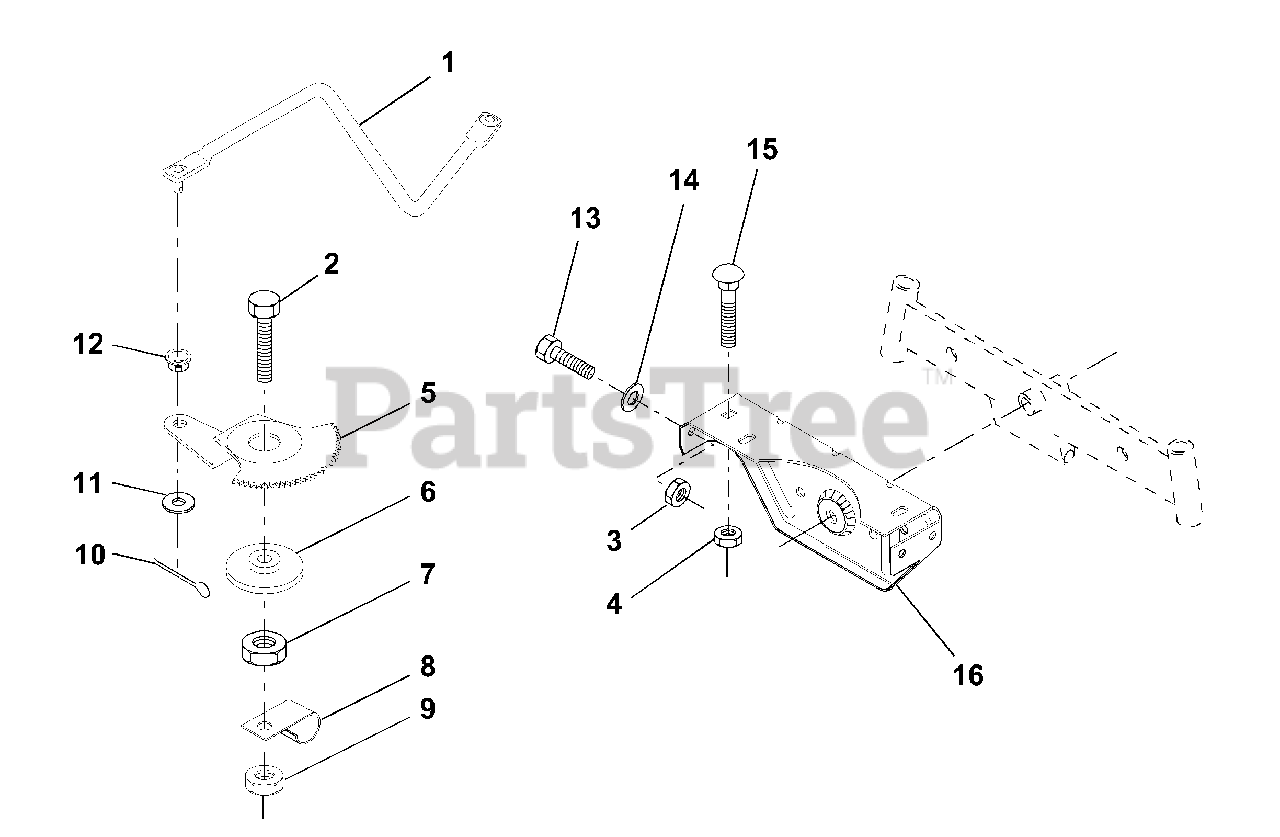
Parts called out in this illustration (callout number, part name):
1	Link, Drag
2	Bolt, Fin Hex 1/2-13 x 1-3/4
3	Nut, Crownlock 5/16-18
4	Nut, Crownlock 3/8-16 UNC
5	Gear, Sector
7	Nut, Heavy Hex Top Lock 1/2-13 UNC
8	Clip, Insulated
9	Nut, Crownlock 3/8-16
10	Pin, Cotter 1/8 x 3/4
11	Washer, 13/32 x 13/16 x 16 Ga.
13	Bolt, Hex Hd. 5/16-18 UNC x 3/4
14	Washer 11/32 x 7/8 x 16 Ga.
15	Bolt, Carriage 3/8-16 UNC x 3/4
16	Support, Front Axle
